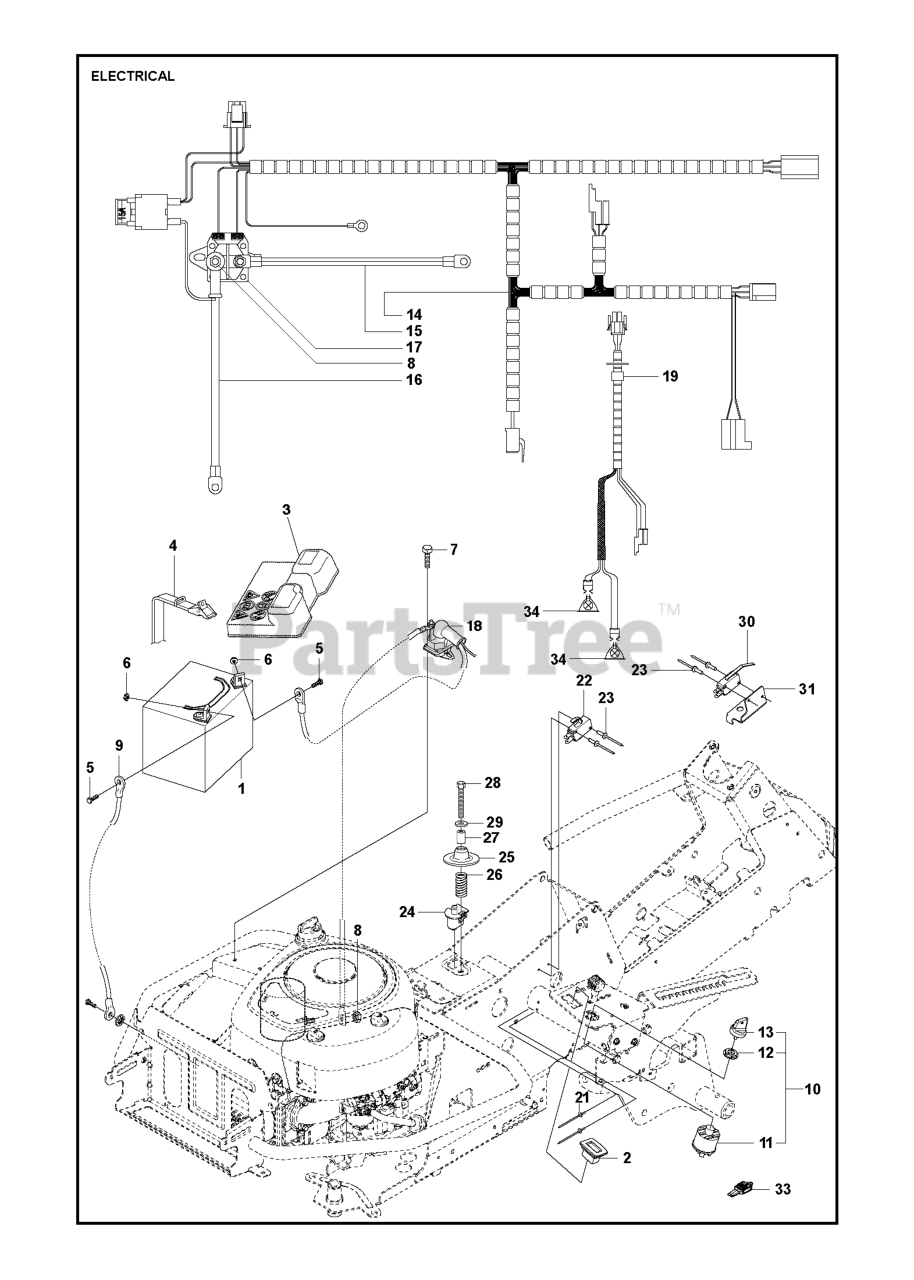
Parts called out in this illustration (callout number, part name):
2	HOUR METER
3	COVER
5	SCREW EHHM
10	IGNITION SWITCH
11	IGNITION SWITCH
13	IGNITION KEY
16	WIRE BATTERY
18	NUT
21	Rivet
22	MICRO SWITCH
22	SWITCH
27	SPACER TUBE
28	SCREW
29	WASHER BRB 8.4X17
30	MICRO SWITCH
